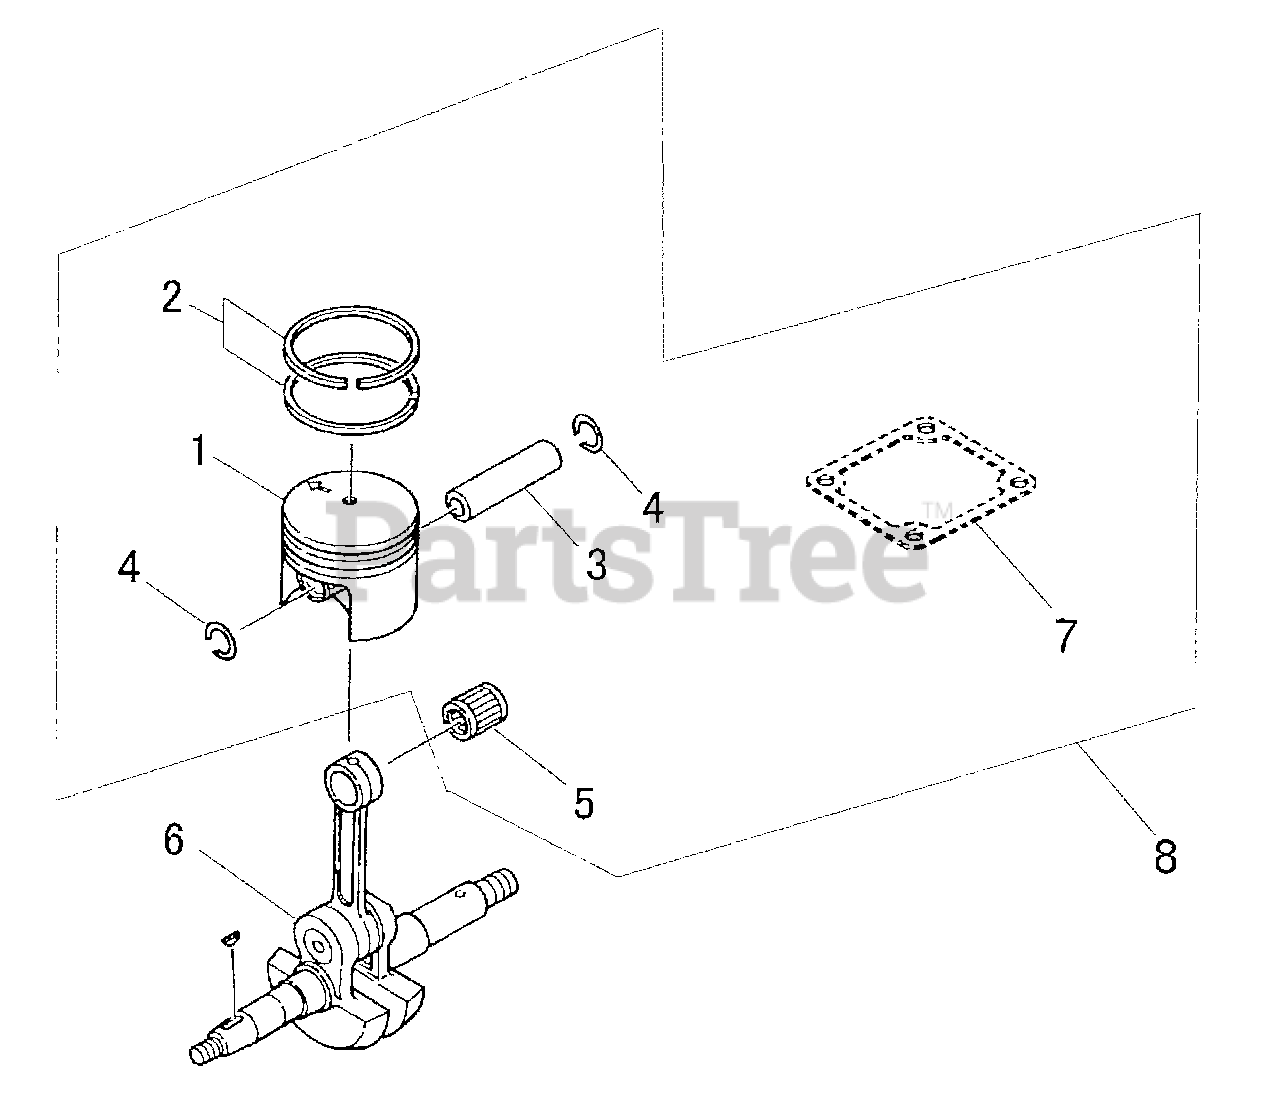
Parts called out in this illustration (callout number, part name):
1	PISTON
2	RING, PISTON
3	PIN, PISTON 10
4	RING, SNAP
5	BEARING, NEEDLE
6	CRANKSHAFT ASSY
7	GASKET, CYLINDER
8	PISTON KIT
